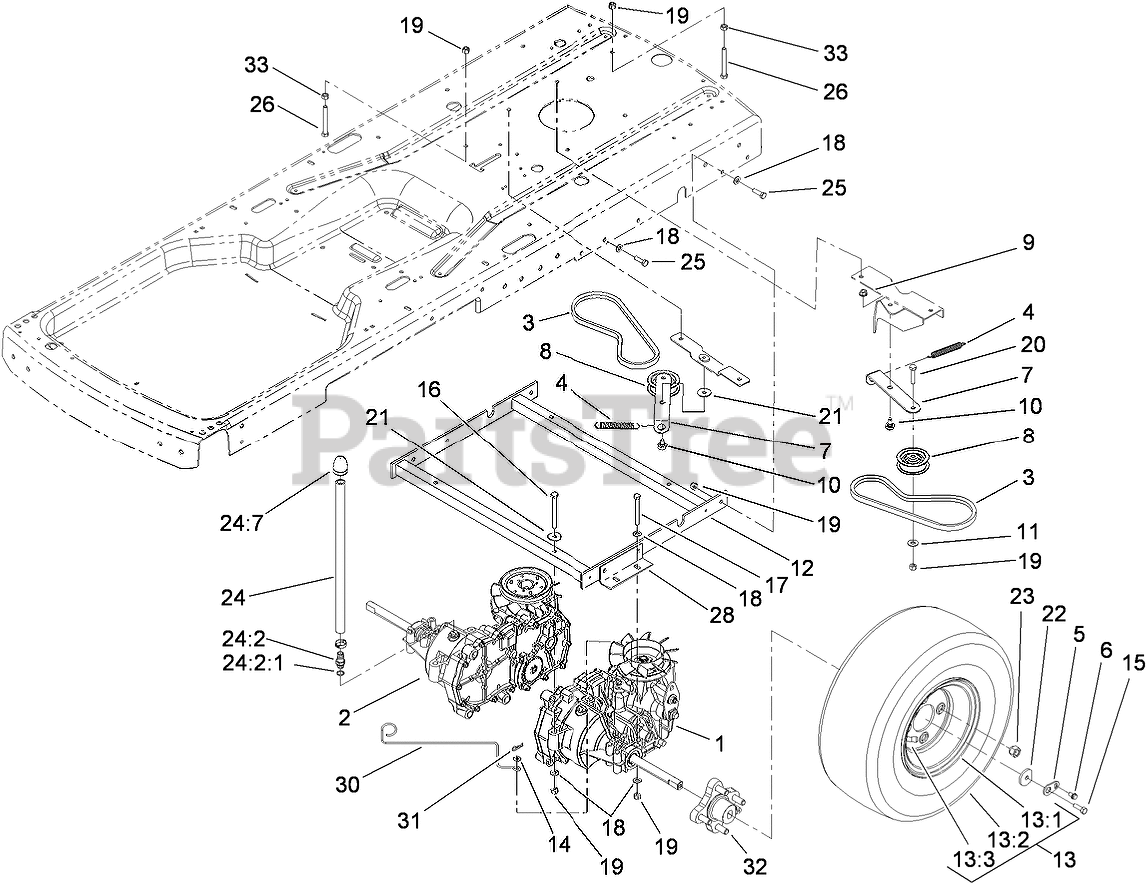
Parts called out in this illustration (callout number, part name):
1	TRANSAXLE-HYDRO, LH
2	TRANSAXLE-HYDRO, RH
3	V-BELT
4	SPRING
5	TAB-LOCKING
6	SCREW-HHF
7	ARM-IDLER
8	PULLEY-IDLER
9	NUT-HF
10	BOLT-SHOULDER
11	WASHER-FLAT
12	HYDRO MOUNT ASM
13	REAR WHEEL ASM
13:3	STEM-VALVE
13:99	TUBE-TIRE
14	WASHER-FLAT
15	SCREW-HH
16	SCREW-HH
17	SCREW-HH
18	WASHER-PLAIN
19	NUT-LOCK, NI
20	SCREW-HH
21	WASHER-PIVOT
22	WASHER-WHEEL
23	NUT-LUG
24	VENT HOSE ASM
24:2	FITTING ASM
24:2:1	O-RING
24:7	CAP VENT ASM
25	SCREW-HH
26	SCREW-HH
28	SUPPORT-HYDRO
30	ROD-BYPASS
31	PIN-COTTER
32	HUB ASM
33	NUT-HEX
